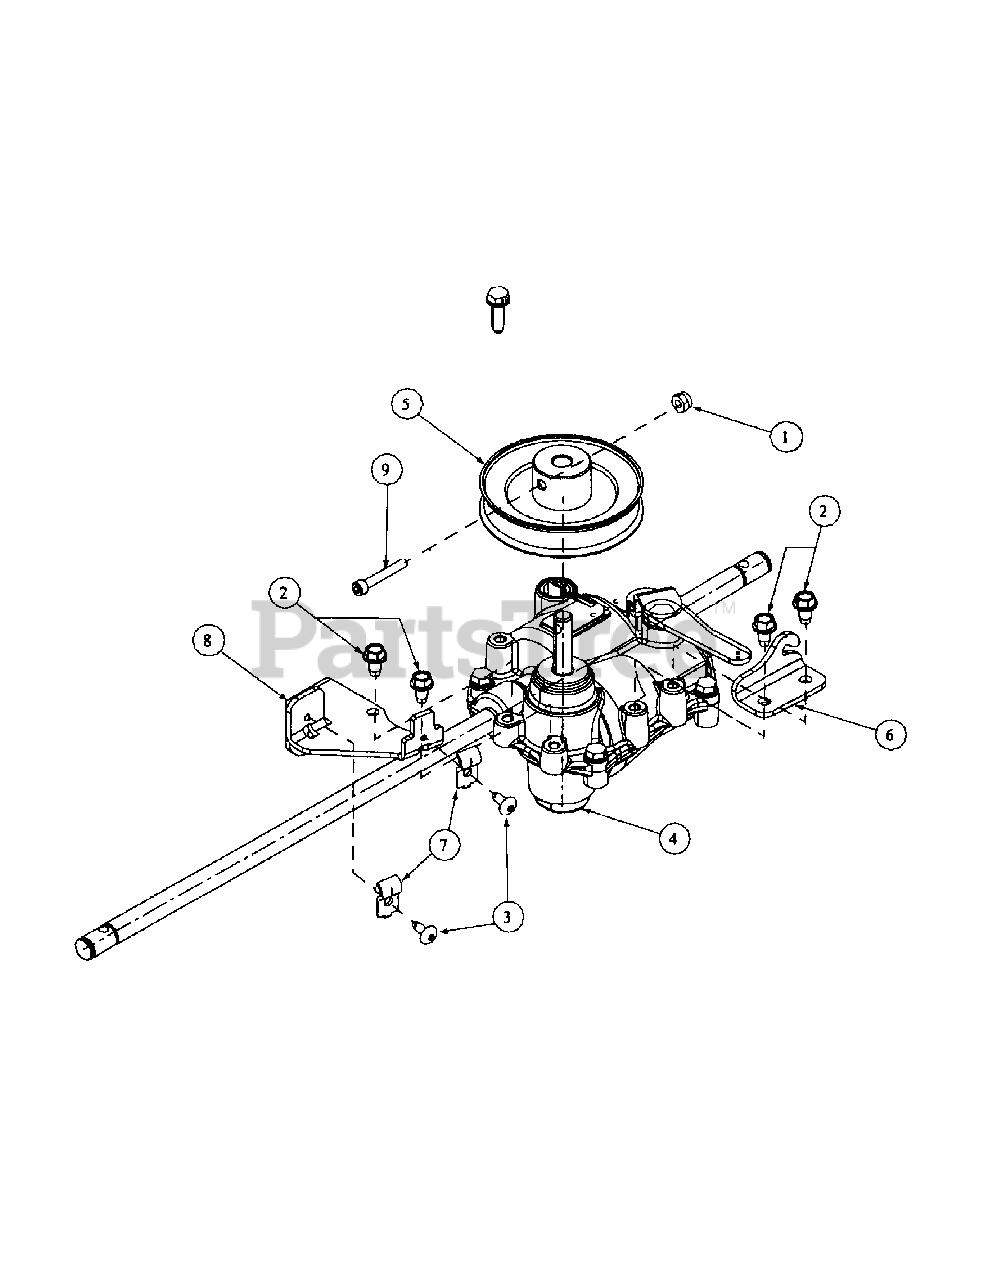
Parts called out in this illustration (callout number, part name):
1	Nylon Lock Nut, #10-24
2	Screw, TT, Hex Index Washer, 1/4-20, 0.500
3	Screw, B, #10-16, 0.500, Trustrx1
4	Complete Transmission, 3-Speed
5	Transmission Pulley, 3/8V x 3.50 OD
6	Spring Bracket Transmission
7	Cable Clamp, 3/16
8	Transmission Clutch Bracket
9	Socket Screw, 10-24 x 1.25
